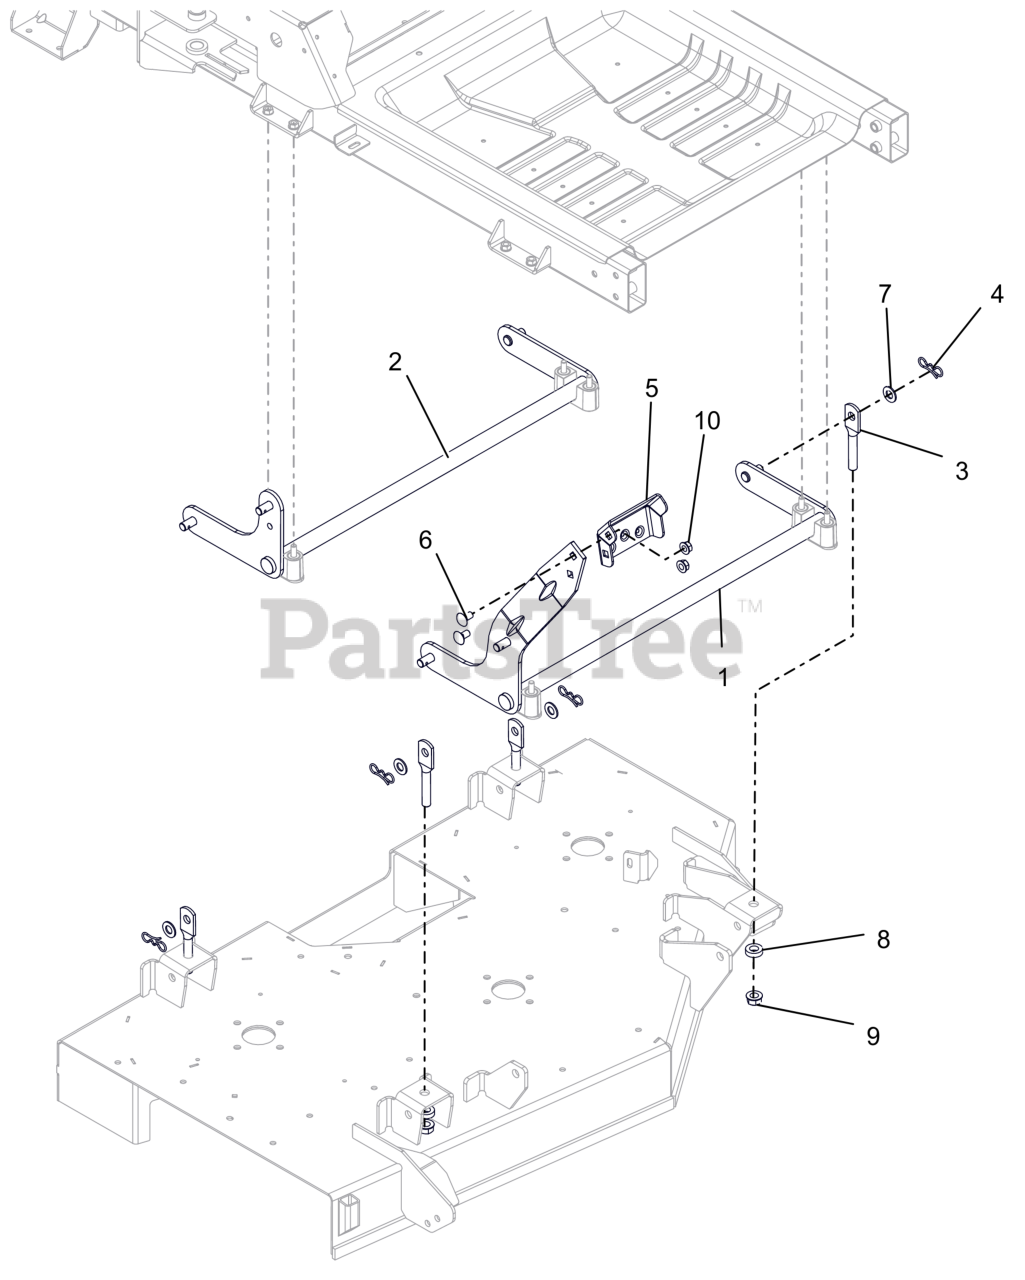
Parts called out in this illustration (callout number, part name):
1	WLDMT, FRONT DECK LIFT PIVOT
2	WLDMT, REAR DECK PIVOT
3	LINK, DECK (HOLE-SHORT)
4	PIN, BOWTIE .091X1.875 ZCC
5	PEDAL, DECK LIFT (BOLT ON)
6	BLT,RHSN .38-16X.75 G5 BFP
7	WSHR-FL-NYL .518X1.000X.080
8	WASHER, RUBBER
9	NUT-LK-CTR-FLG .500-13 GG ZCC
10	NUT-LK-CTR-FLG .375-16 GF ZCC
